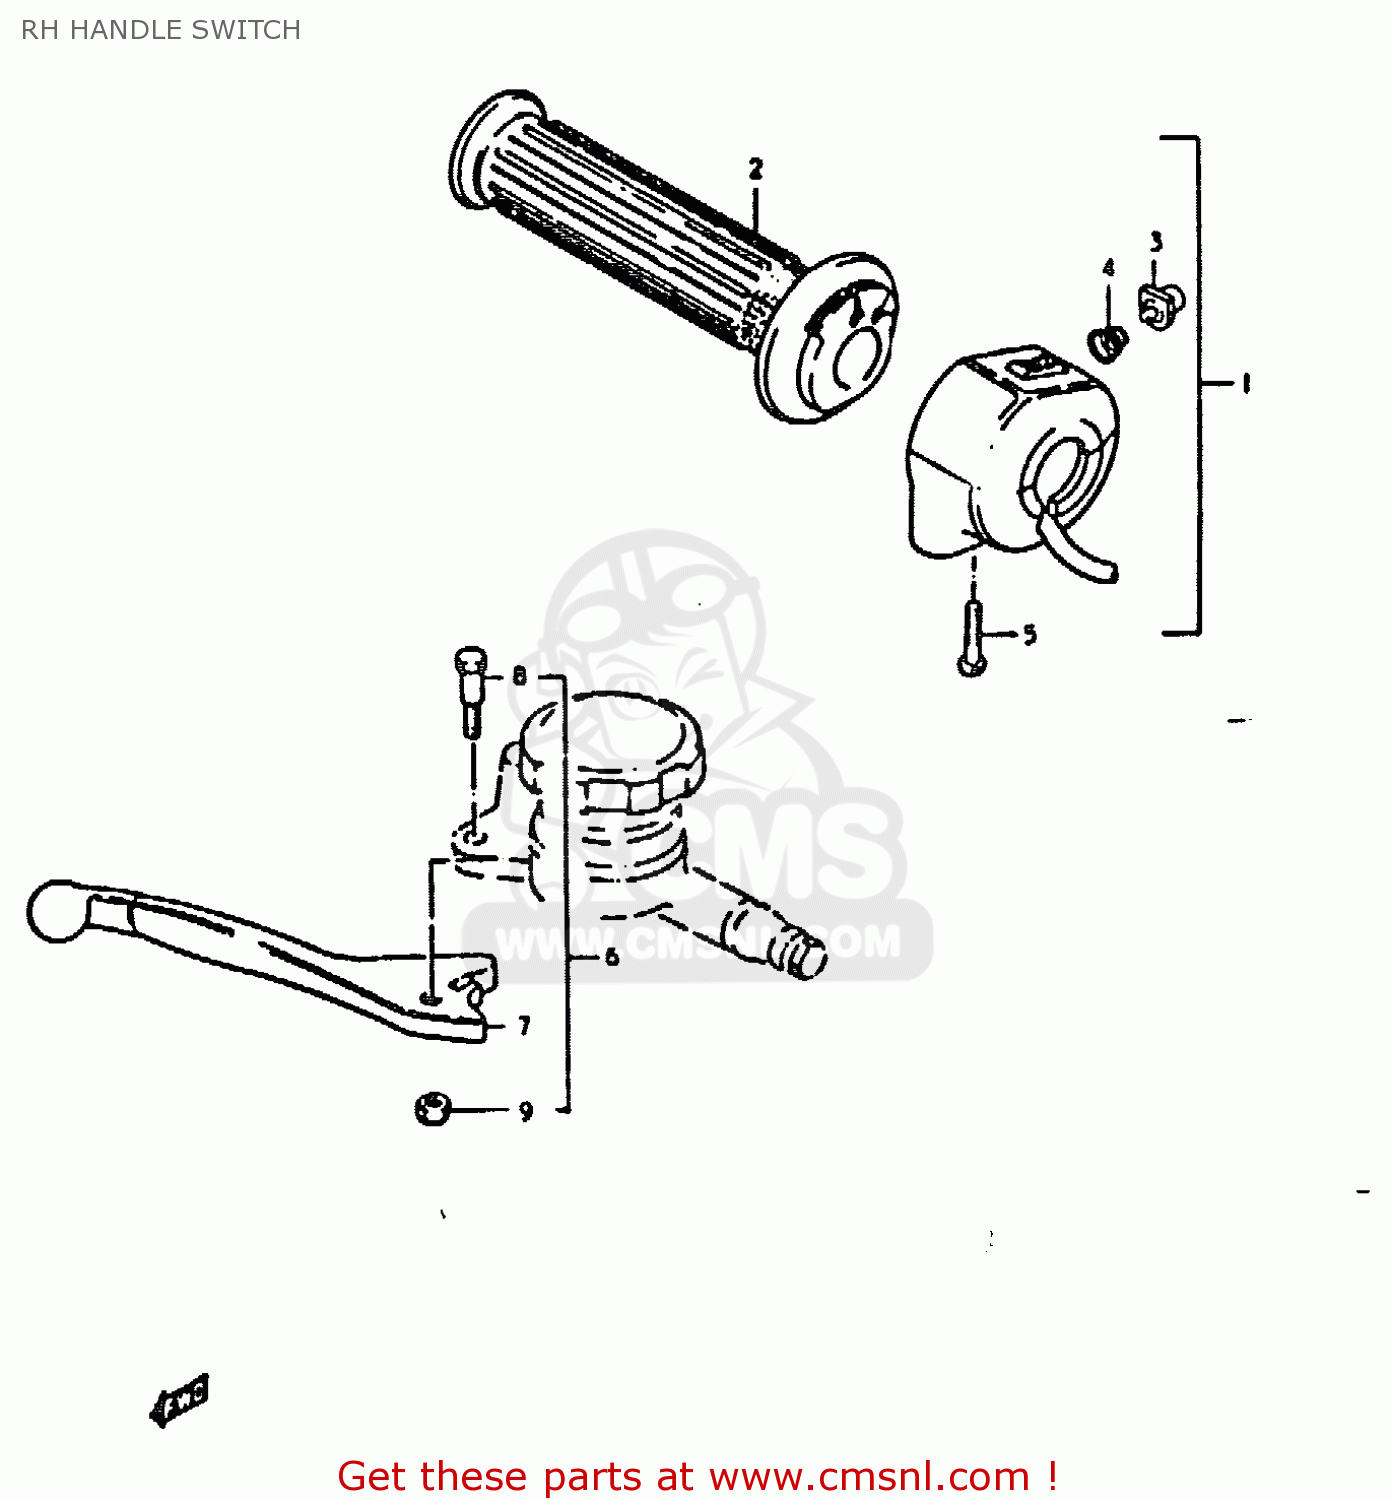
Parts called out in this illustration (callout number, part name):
1	GRIP ASSY, THROTTLE
2	GRIP,THROTTLE
3	BUTTON
4	SPRING
5	SCREW
6	LEVER ASSEMBLY,BRAKE
7	LEVER,BRAKE
8	BOLT,LEVER
9	NUT 6MM
